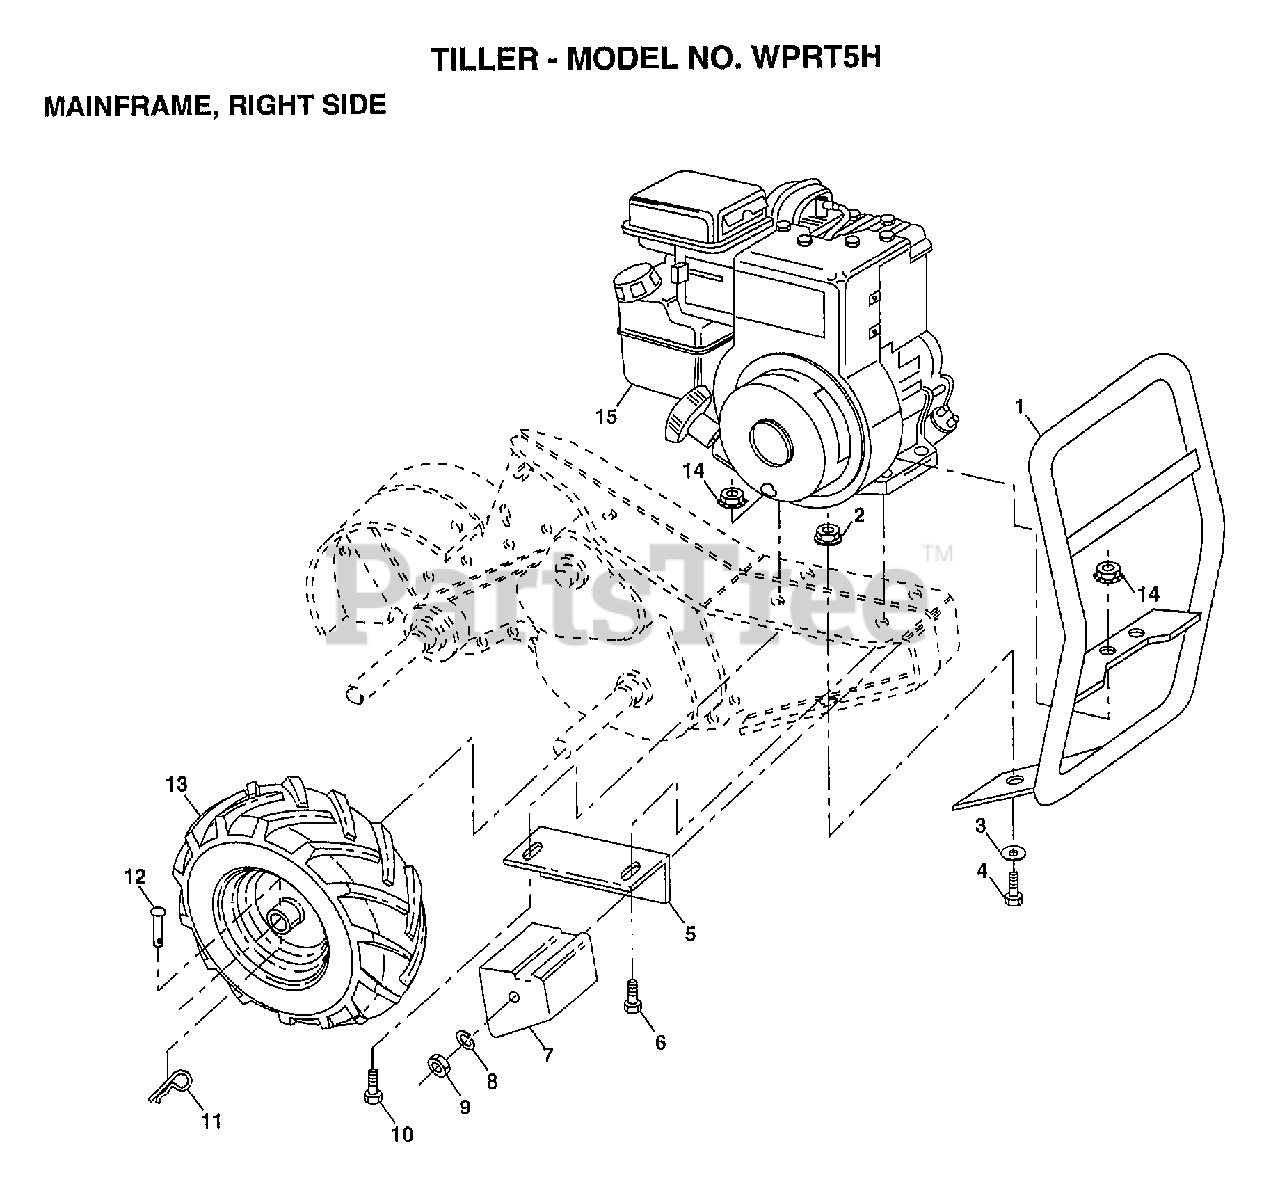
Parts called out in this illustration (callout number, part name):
1	BUMPER ASM.TILLER
2	LOCKNUT TI
3	WASHER
4	BOLT
5	BRACKET RH CRT
6	BOLT
7	COUNTERWEIGHT CRT
8	LOCKWASHER
9	NUT.HEX.3/8-16UNC
10	BOLT.HEX.5/16-1.5
11	RETAINER M
12	RIVET.DRILL.1.75
13	TIRE TI
